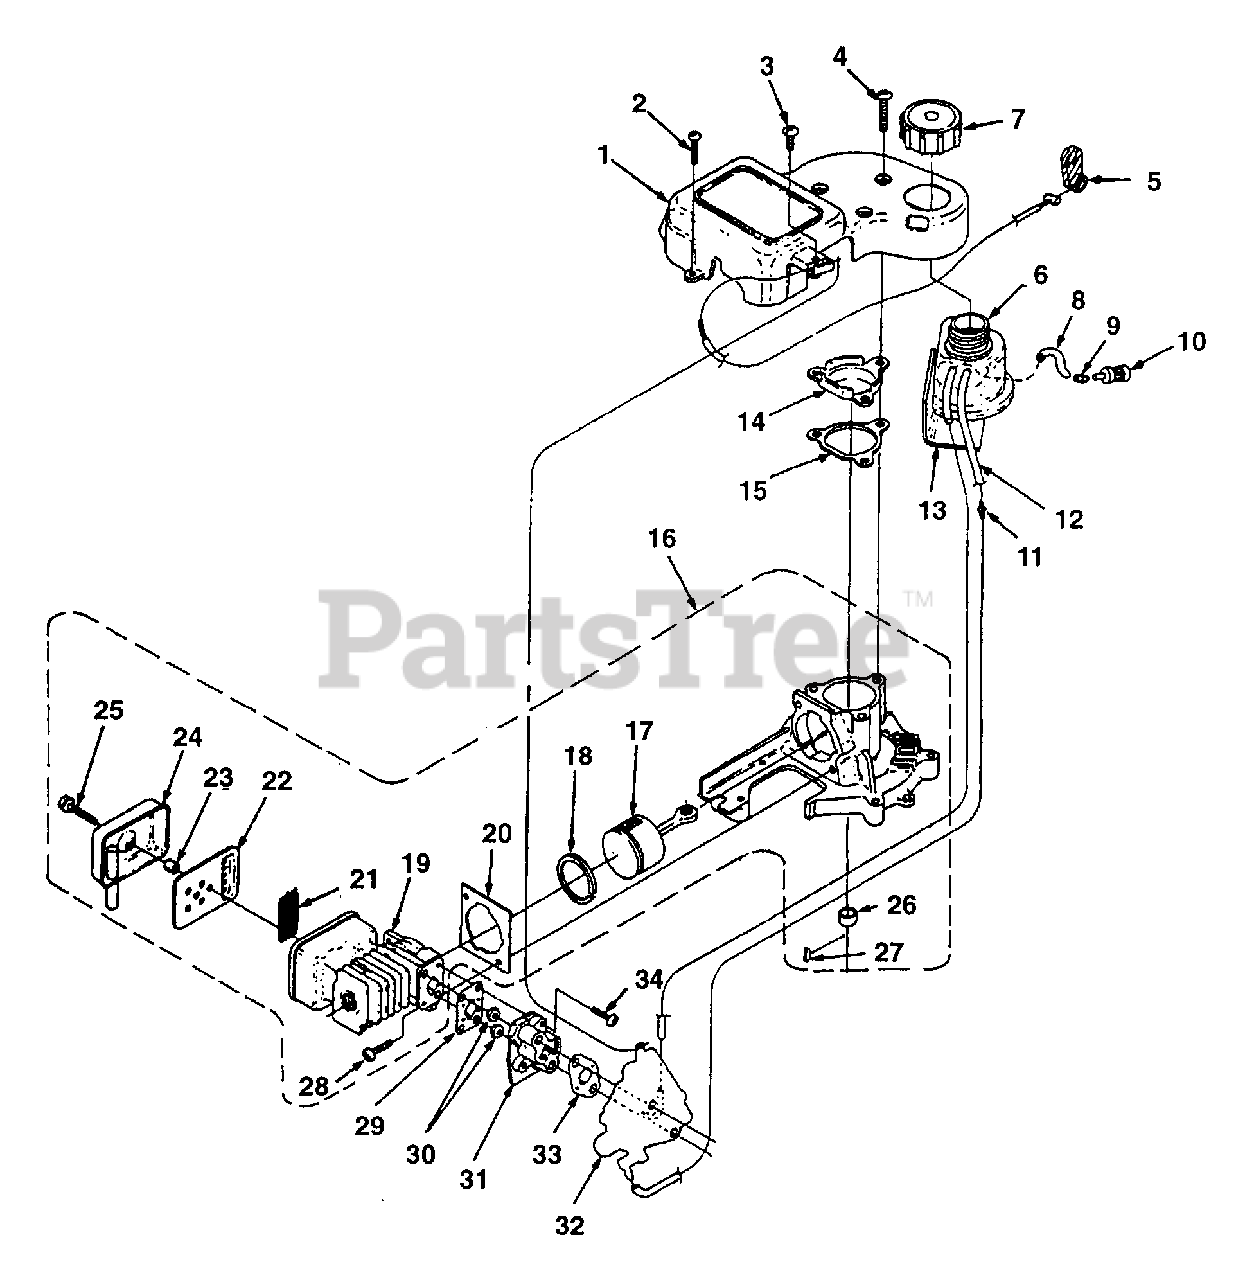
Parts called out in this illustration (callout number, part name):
1	COVER-Engine
2	SCREW-Thread Form. (#8 x 3/4")
3	SCREW-Thread Form. (#10 x 1/2")
4	SCREW-Thread Form. (10-24 x 3/4")
5	LEVER-Trigger
6	FUEL TANK ASSEMBLY
7	CAP-Fuel
8	TUBING-Rubber (5 1/2")
9	CLAMP-Wire
10	FILTER-Fuel
11	FITTING
12	TUBING-Rubber (6 1/4")
13	SPACER-Fuel Tank
14	CRANKCASE COVER
15	GASKET-Crankcase
16	SHORT BLOCK
17	PISTON & ROD
18	RING-Piston
19	CYLINDER & MUFFLER ASSEMBLY
20	GASKET-Cylinder
21	SCREEN-Spark Arrestor
22	BAFFLE-Muffler
23	SPACER-Muffler
24	COVER-Muffler
25	SCREW-Thread Form. (8-32 x 1")
26	SPACER
27	KEY-Woodruff
28	SCREW-Machine (10-24 x 3/4")
29	GASKET-Heat Dam
30	NUT-Hex (10-24)
31	HEAT DAM
32	CARBURETOR KIT
33	GASKET-Carburetor
34	SCREW-Thread Form. (10-24 x 1")
